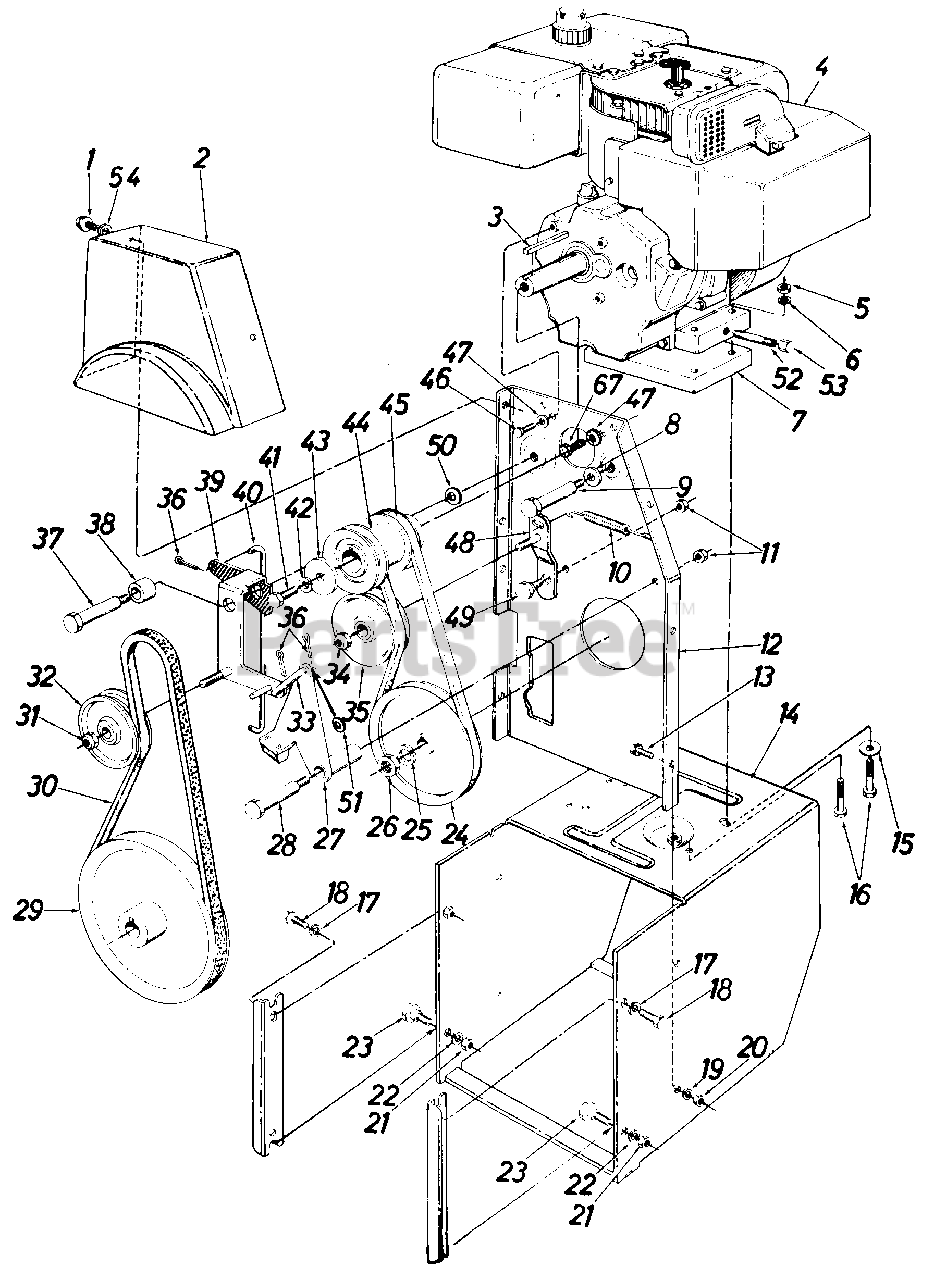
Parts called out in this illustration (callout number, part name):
1	Hex Wash. Self-Tap Scr. 5/16-24 x .50" Lg.
2	Belt Cover
3	Sq. Key 1/4" X 1.50" Lg.
4	Engine
5	Hex Nut 5/16-18 Thd.
6	L-Wash. 5/16" Scr.
7	Engine Spacer Ass'y.
8	Bell-Wash. .40 I.D. x .88 O.D.
9	Stud 3/8-16 x 3.37" Lg.
10	Ext Spring .38 O.D. x 3.18" Lg.
11	Hex Cent. L-Nut 3/8-16 Thd.
12	Engine Brkt. Ass'y.
13	Hex Sems Scr. 5/16-18 x .75" Lg.
14	Frame Ass'y.
15	Fl-Wash. .345 I.D. x .75 O.D. x .060
16	Hex Bolt 5/16-18 x 2.50" Lg.
17	L-Wash. 3/8" I.D. H.D.
18	Pilot Scr. 3/8-16 x .88" Lg.
19	L-Wash. 5/16" I.D.
20	Hex Nut 5/16-18 Thd.
21	Hex Nut 3/8-16 Thd.
22	L-Wash. 3/8" I.D. H.D.
23	Shld. Bolt .498" Dia. x .340" Lg.
24	V-Pulley .628 I.D. x 7.50 O.D.
25	L-Wash. 5/8" I.D.
26	Hex Ins. Jam L-Nut 5/8-18 Thd.
27	Brake Brkt. Ass'y.
28	Shld. Bolt .498" Dia. x 2.00" Lg.
29	V-Pulley .875 I.D. x 10.12 0. D.
30	"V"-Belt 1/2 " X 45.0" Lg.
31	Hex Ins. Jam L-Nut 3/8-24 Thd.
32	Fl-Idler w/Flanges 3.0 O.D.
33	Brake Linkage Ass'y.
34	Hex Ins. Jam L-Nut 3/8-24 Thd.
35	Flat Idler Pulley
36	Int. Cot. Pin 5/16" Dia.
37	Shld. Bolt .625 Dia. x 2.750" Lg.
38	Spacer .75 O.D. x 1.00" Lg.
41	Hex Bolt 3/8-24 x 1.25" Lg.
42	L-Wash. 3/8" I.D. H.D.
43	Fl-Wash.
44	Engine Pulley
45	"V"-Belt 3/8 x 35.5 Lg.
46	Hex Bolt 5/16-24 x .62" Lg.
47	Bell-Wash. .345 I.D. x .88 O.D. x .060
48	Drive Idler Brkt. Ass'y.
49	Shld. Bolt .625" Dia. x .170" Lg.
50	Bell-Wash. .40 I.D. x 1.12 O.D.
51	Fl-Wash. .34 I.D. x .750 O.D. x .05
52	Pipe Nipple 1/2" Pipe Thd. x 3.00" Lg.
53	Hex Bolt 1/4-18 Pipe Thd.
54	Fl-Wash. .340 I.D. x .62 O.D. x .62
